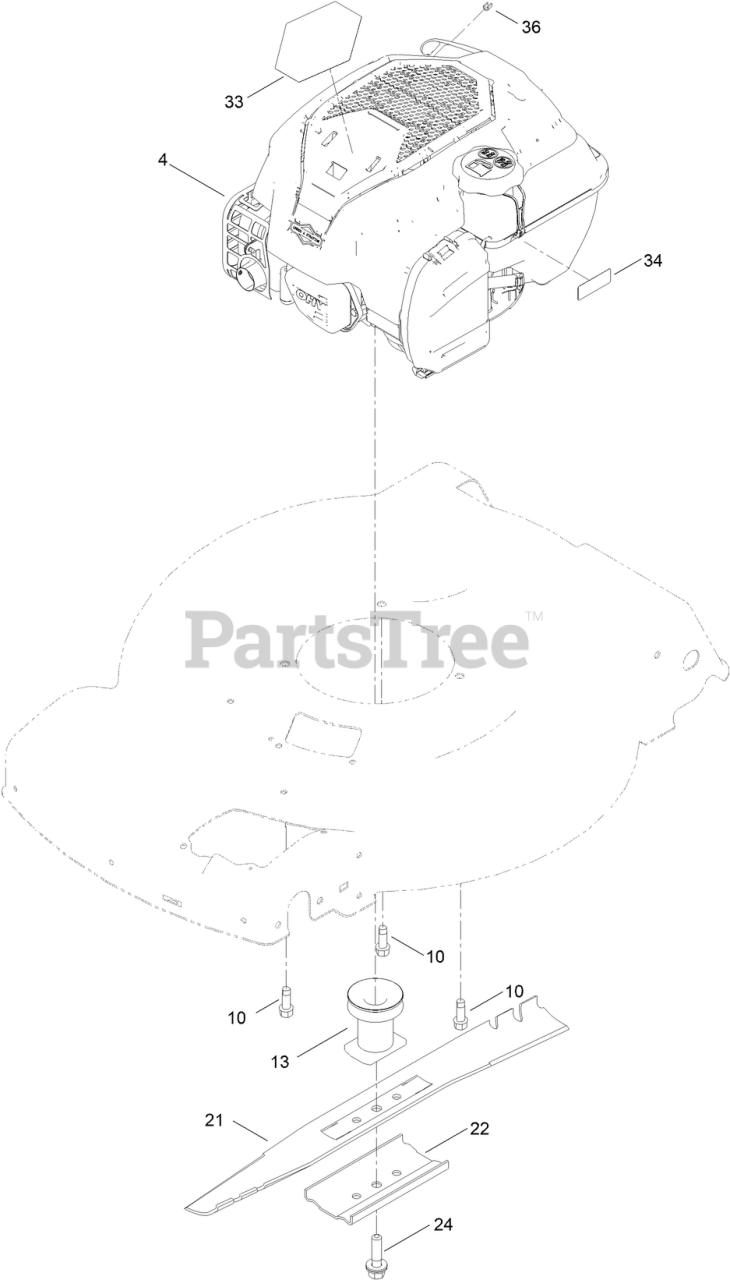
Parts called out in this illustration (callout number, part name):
10	SCREW-TAPTITE
13	DRIVER-BLADE
22	SUPPORT-BLADE
24	BOLT-BLADE
33	DECAL-SHROUD
34	DECAL-LEVEL, FUEL
36	STOP-ROPE
